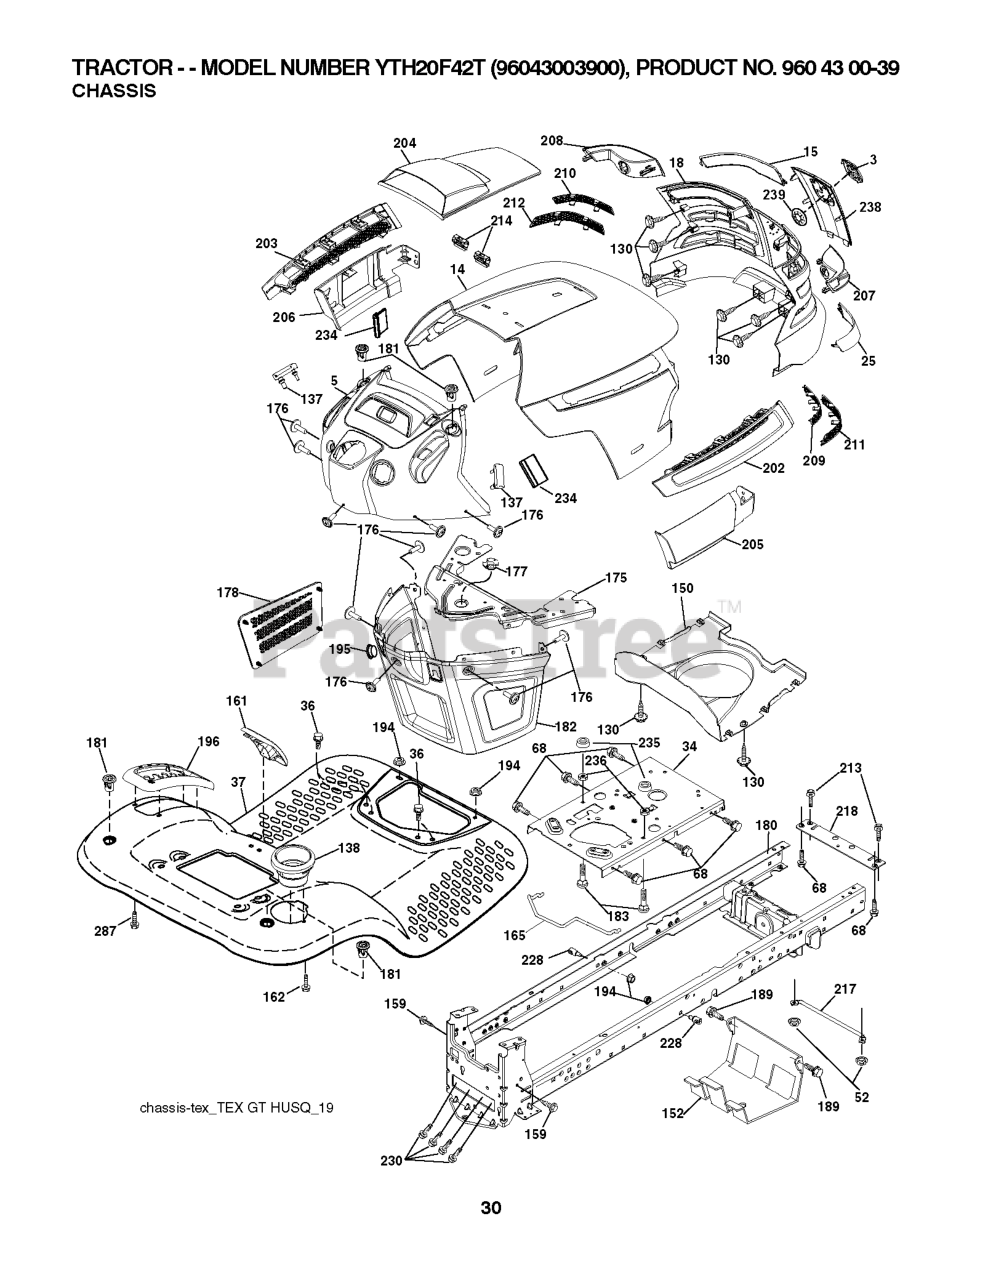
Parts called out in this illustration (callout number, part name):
4	RP LOGO
5	DASH.ASM.HUSQ.GT
6	NUT PUSH M
14	HOOD
15	LENS.LH.TEX.GT.HUSQ.CL
18	GRILL.ASM.HUSQ.TG/CRD.W/TRIM
25	LENS.RH.TEX.GT.HUSQ.CL
34	PLATE.ENGINE.WELDED.CHASSIS
36	SCREW 5/16"
37	FENDER.TLT.W/CPH.W/FW.ORANGE
52	LOCKNUT
68	Screw 5/16-18 x 1/2 Hex, Self Tapping 5/16-18 x 1/2
130	SCREW.#10 X 0.750.BOS
137	BUMPER DASH
138	CUPHOLDER.TL.TEX.418
150	AIR.DUCT.TEXGT.HUSQ.SV
152	SHIELD.BROWNING.W/TEX
161	WINDOW FUEL
162	SCREW.HI-LO.CONSOLE
165	SUPPORT.TANK.REAR.W/TEX
175	PLATE.CROSSMEMBER.HUSQ
176	SCREW.#10-24X5/8.RN.QU
177	BUSHING, STEERING
178	CARGO.ASM.NET.TXGT.W/C
180	CHASSIS
181	BUSHING.MNT.FEND.CRGO.
182	DASH.LOWER.COMMON.12V.ADAPTOR
183	BOLT.5/16-18X1-1/4 FULL.THREAD
189	SCREW
194	NUT LOCK HEX FLANGE 5/16-18
195	PLUG.HOLE.DASH.LOWER.12V.BLK
196	RP CONSOLE.ASM.DECKLFT.GR/RBT.
202	VENT.SIDE.HOOD.HUSQ.RH.GREY
203	VENT.SIDE.HOOD.HUSQ.LH.GRAY
204	VENT.ASM.TORPHD.HUSQGT.LOGO.CL
205	SKIRT.HOOD.SIDE.HUSQ.RH.GREY
206	SKIRT.HOOD.SIDE.HUSQ.LH.GREY
207	BEZEL.RH.TEX.GT.HUSQ
208	BEZEL.LH.TEX.GT.HUSQ
209	INSERT.HEX.GRILL.HUSQ.GREY
210	INSERT.HEX.GRILL.HUSQ.
211	INSERT.HEX.GRILL.HUSQ.
212	INSERT.HEX.GRILL.HUSQ.
213	BOLT
214	CLIP.RETAINER.TINNER.
217	ROD.PIVOT.HOOD
218	X-PIECE.HOOD.STOP.NON/
228	STUD.FASTNER.W/ANTI-ROTATE
230	SHOULDER BOLT 5/16-18TT
234	BUMPER.HOOD.TEX.HUSQVARNA
235	SPACER FENDER
236	NUT.CENTERLOCK.5/16-
287	SCREW 1/4X20
